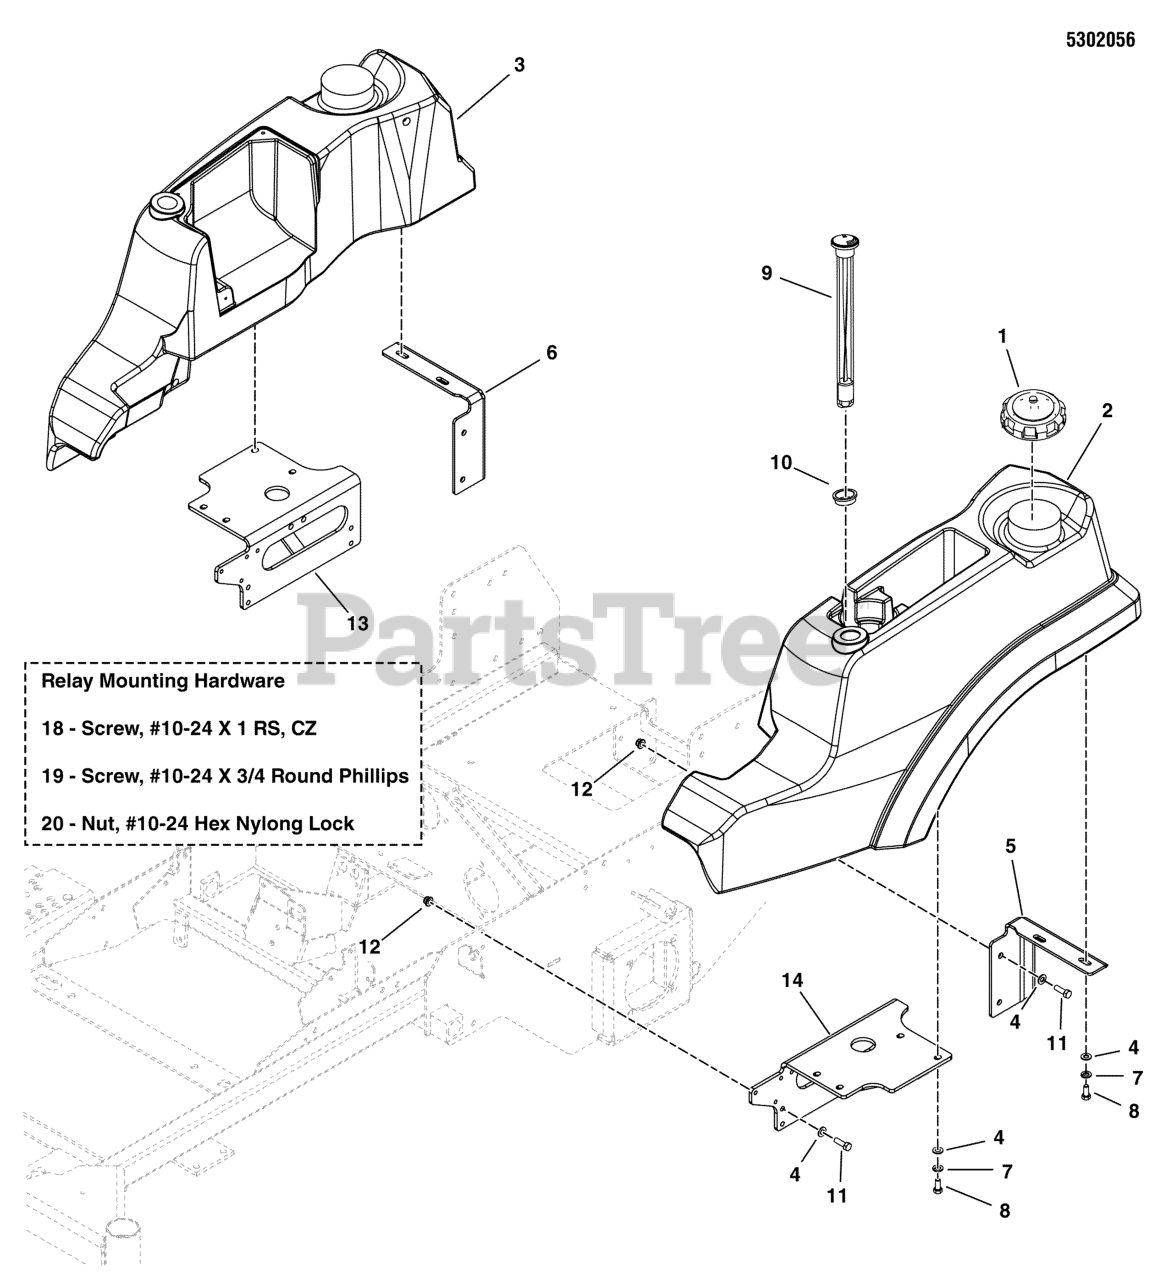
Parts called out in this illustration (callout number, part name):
1	FUEL CAP, 3.5", NON VENTED, DIESEL (GRN)
2	TANK, FUEL, LH, S175X
3	TANK, FUEL, RH, S175X
4	WASHER, 5/16" SAE
5	WELD, TANK MOUNT, REAR, LH - RED
6	WELD, TANK MOUNT, REAR, RH - RED
7	WASHER, 5/16 LOCK CZ
8	BOLT, 5/16-18 X 3/4 GD5
9	GAUGE, FUEL, 12
10	GROMMET, FUEL GAUGE
11	BOLT, 5/16-18 X 1 GD5 YZ
12	NUT, 5/16-18 HEX NYLOCK FLANGE
13	WELD, MOUNT, TANK, RH - RED
14	WELD, MOUNT, TANK, LH - RED
15	WASHER, 3/8 SAE
16	BOLT, 3/8-16 X 1" GD5 CZ
17	NUT, 3/8-16 HEX NYLOCK FLANGE
18	SCREW, #10-24 X 1 RS, CZ
19	SCREW, #10-24 X 3/4 ROUND PHILLIPS
20	NUT, #10-24 HEX NYLON LOCK
